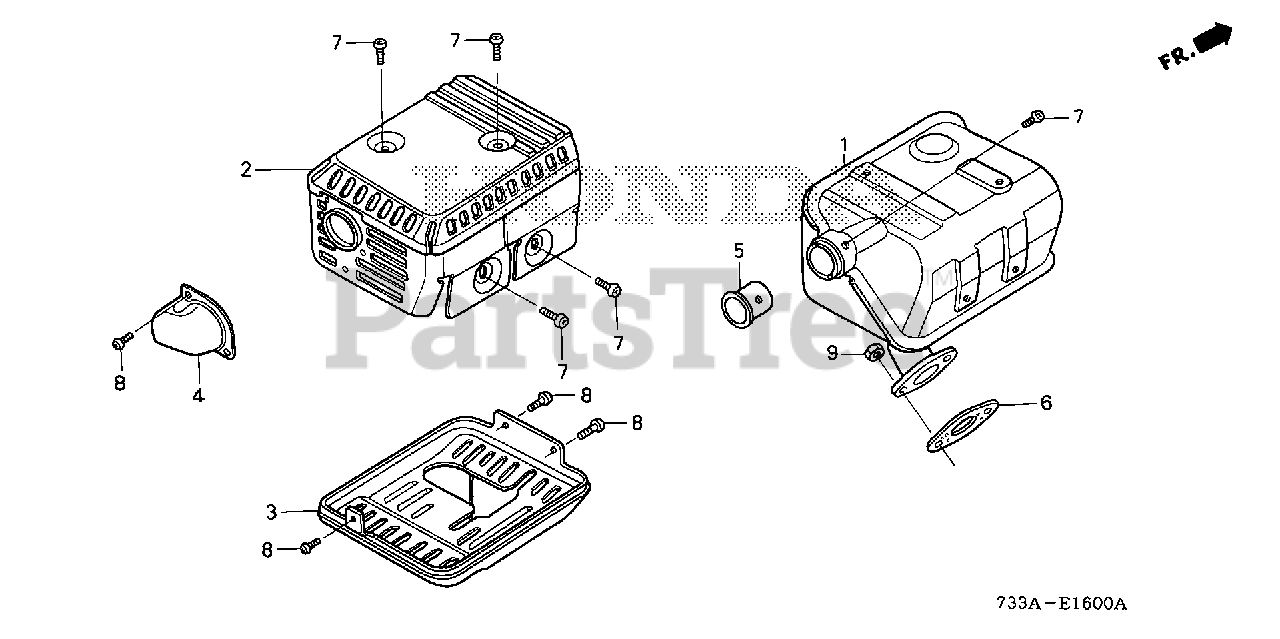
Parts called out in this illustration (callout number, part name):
1	MUFFLER (STD)
2	PROTECTOR, MUFFLER (STD) (BLACK)
4	DEFLECTOR, MUFFLER
5	PIPE, TAIL
6	GASKET, MUFFLER
7	SCREW, TAPPING (5X8)
8	SCREW, TAPPING (4X6)
9	NUT, HEX. (8MM)
